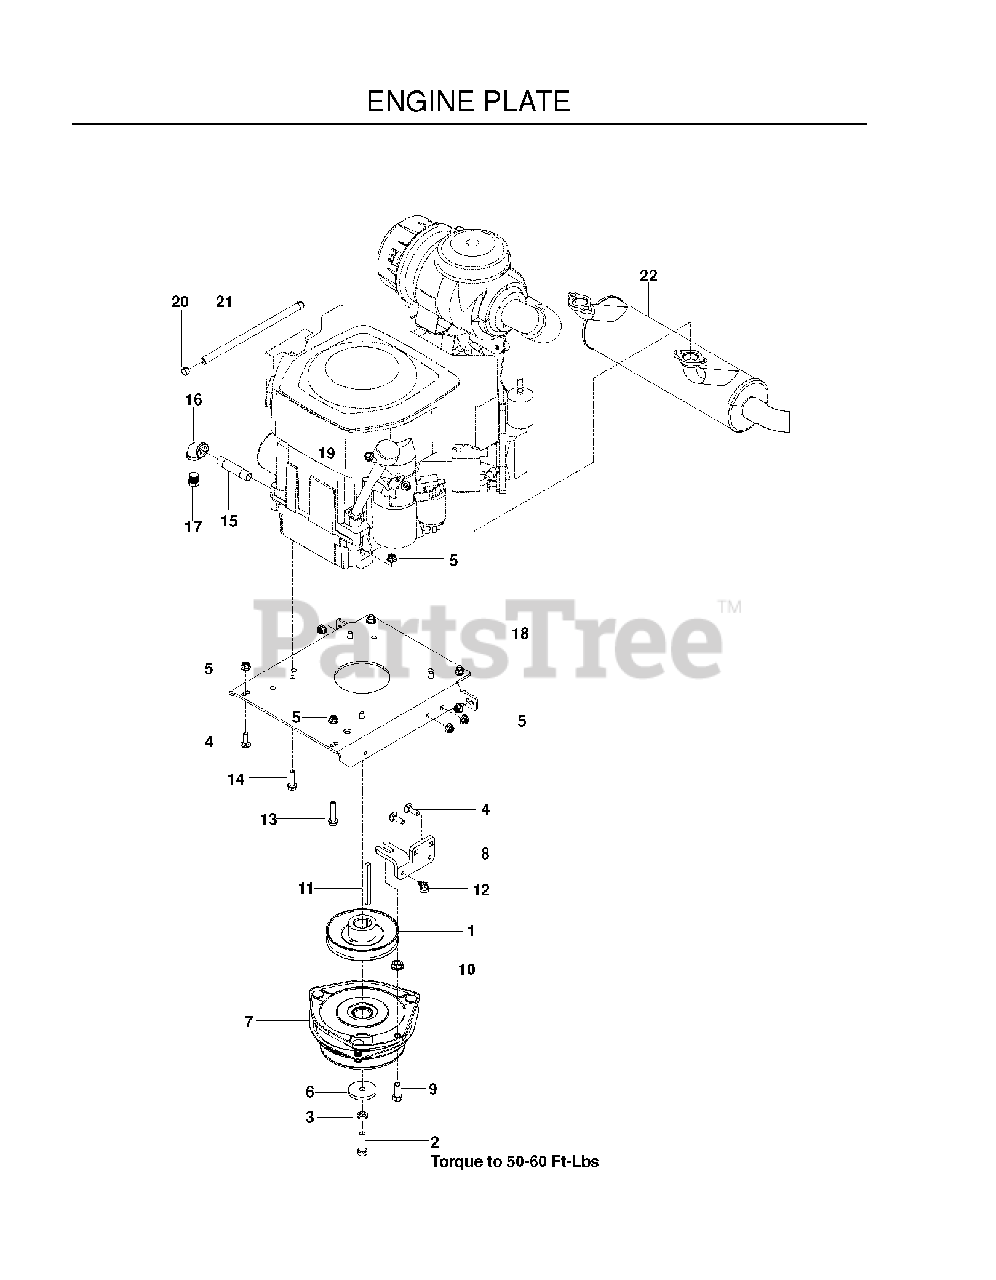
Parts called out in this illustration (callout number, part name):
1	PULLEY, ENGINE
2	HCS 7/16F X 1 1/2
3	WASHER 7/16 LOCK
4	RHSNB 5/16C X 1
5	5/16-18 NYLOC FLANGE NUT
6	BLADE WASHER
7	CLUTCH, GT3.5
8	STOP, CLUTCH, OGURA
9	HCS 7/16-14 X 1 GR 5 ZD
10	NUT 7/16C WHIZ
11	KEY, 1/4 SQ X 3.5
12	TIE WRAP, 8-3/8", W/CLIP
13	HHFS 5/16-18 X 2.25 GD 5
14	HHFS 5/16-18 X 1.5 GD 5
15	PIPE NIPPLE 3/8 X 3
16	90 DEG.ELBOW 3/8NPT
17	PLUG, DRAIN 3/8 NPTF
18	PLATE.ENGINE.BLACK
19	HHFS 5/16-18 X 3/4
20	HOSE CLAMP
21	FUEL LINE 5"
22	MUFFLER.CV23.THRU.CV30
